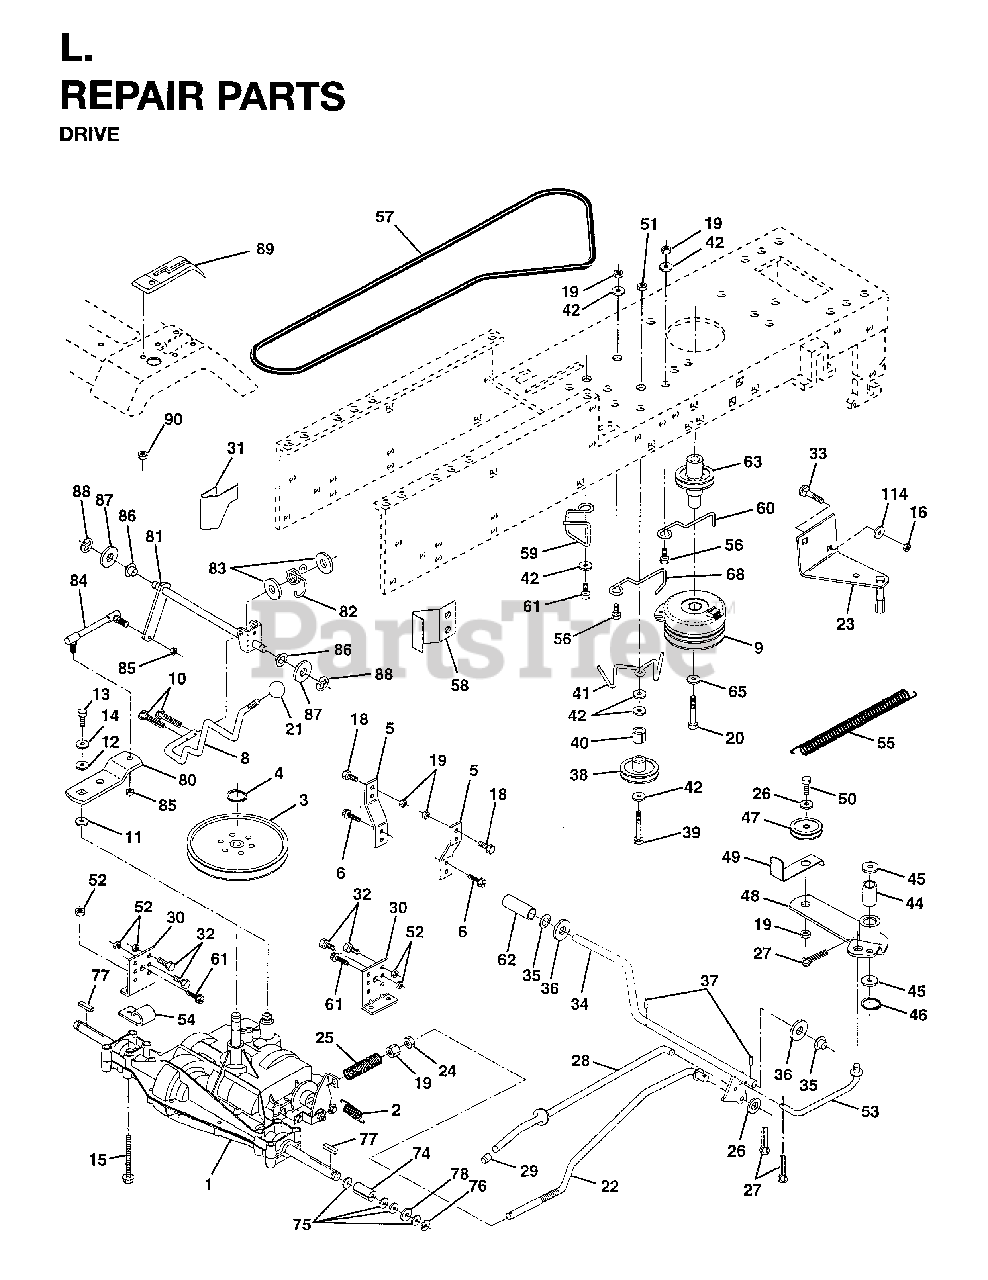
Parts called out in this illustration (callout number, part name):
1	TRANSAXLE NLA
2	SPRING,BRAKE RETURN
3	PULLEY TRANS
4	RETAINING RING
5	STRAP TORQUE
6	BOLT
8	SHIFT ROD
9	CLUTCH, ELECTRIC
10	PIN COTTER
11	WASH-SHFT PLT LT
13	BOLT 1/4-28X3/4
14	LOCKWASHER
15	BOLT HEX 5/16-18 GR 5
19	LOCKNUT
20	BOLT
21	KNOB.DUCKHEAD.1/2
22	ROD BRAKE
23	BRACKET ASM MTG
24	NUT.HEX.3/8-16UNC
25	SPRING ROD LT
26	WASHER
27	COTTER PIN
28	ROD BRAKE PARK LT
29	PLUNGER CAP
30	BRACKET TRANSAXLE
31	KEEPER BELT LH
32	BOLT
33	BOLT
35	BEARING.NYLON
37	DRIVE PIN
38	PULLEY.IDLER.FLAT
40	SPACER T
42	WASHER
44	BEARING LT
45	WASHER LT
46	KLIP RING
47	IDLER PULLEY
48	ARM IDLER
49	RETAIN BELT
50	BOLT
51	LOCKNUT
52	LOCKNUT
53	LINK, CLUTCH LT
55	SPRING, RETURN LT
56	BOLT
57	BELT, V GROUND DRIVE 95 25
59	KEEPER CENTER SPAN
60	KEEPER BELT ENGLH
62	COVER, PEDAL
63	PULLEY CLU ELEC
65	LOCKWASHER
68	KEEPER,BLT ENG LT
74	SPACER AXLE
76	E-RING LT
77	SQUARE KEY
80	ARM SHIFT
81	SHAFT ASMBLY
82	SPRING,TORSION
84	ROD TIE 20"
85	NUT
86	BUSHING.STEERING.ROD
88	KLIP RING
89	CONSOLE SHIFT
96	RETAINER M
112	WASHER - 26X6.5X1.6
113	STRAP TORQUE LH LT
